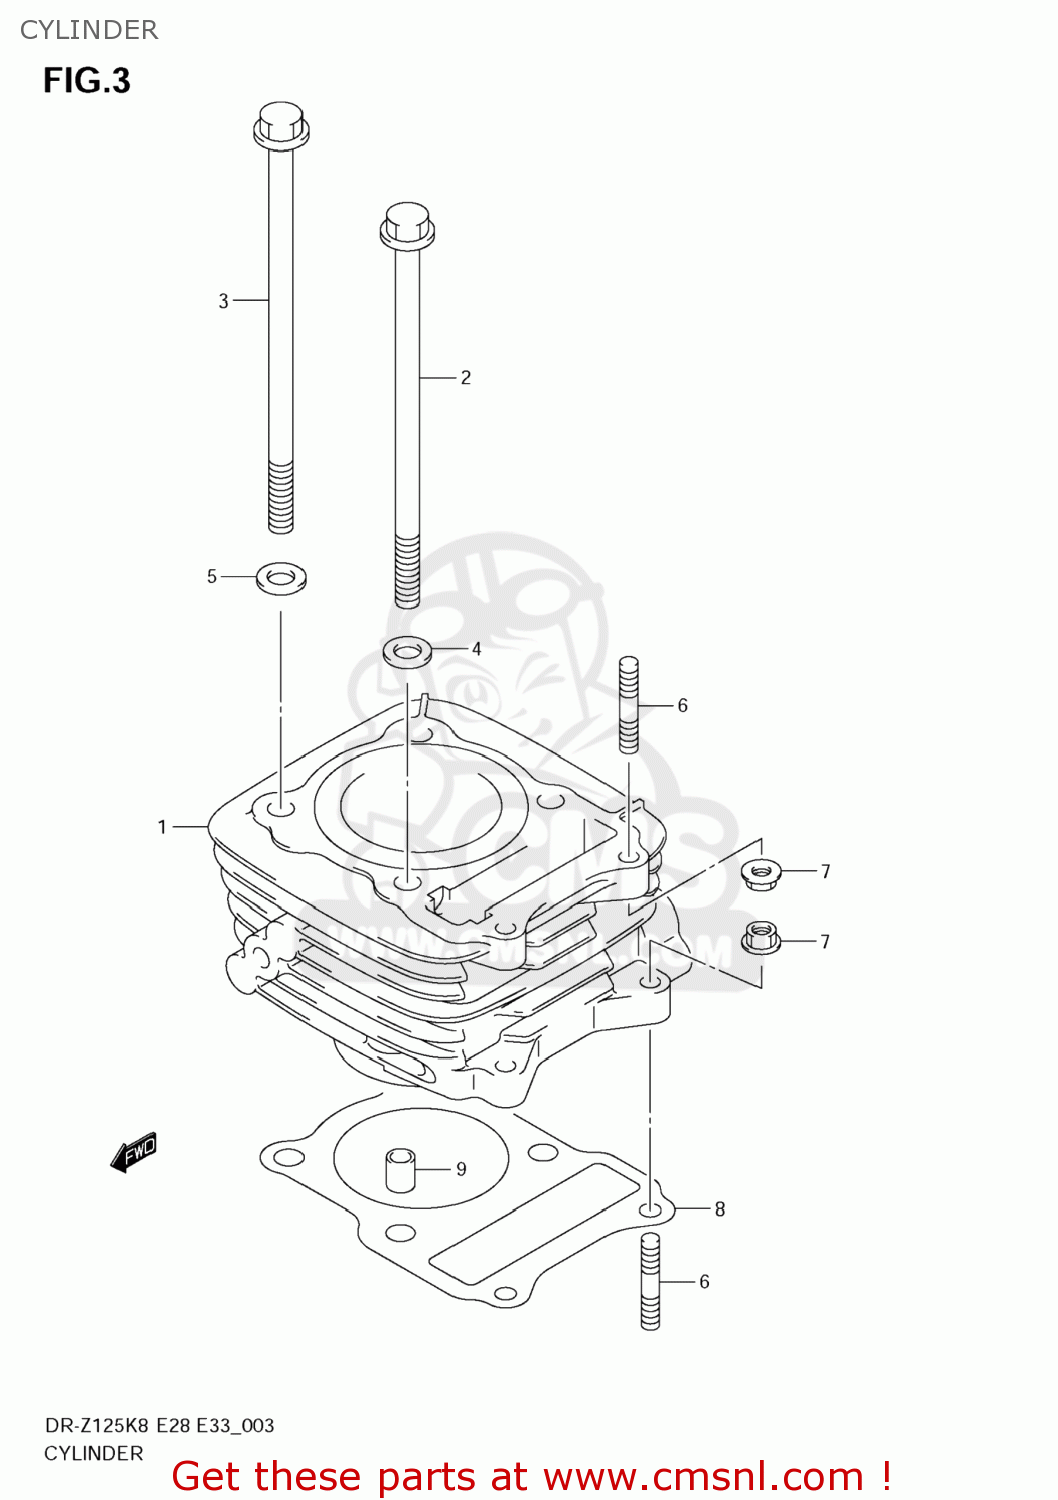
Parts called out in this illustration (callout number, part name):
1	CYLINDER
2	BOLT(8X155)
3	BOLT(8X165)
4	WASHER(8.5X19X2.3)
5	GASKET(8.5X17X2.3) (NAS)
6	BOLT,STUD
7	NUT
8	GASKET,CYLINDER (NAS)
9	PIN
